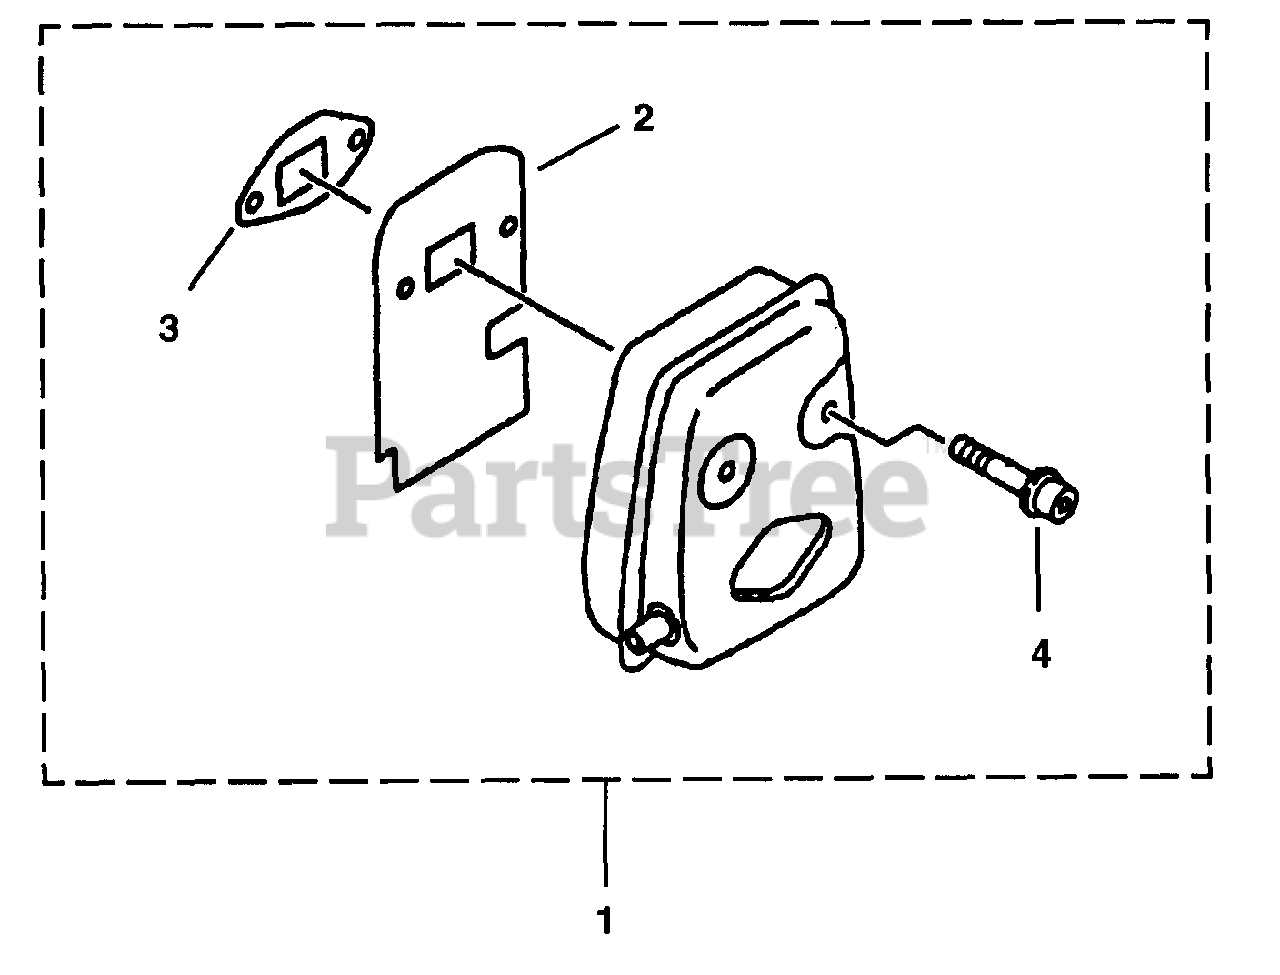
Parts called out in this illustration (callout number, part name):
1	MUFFLER ASSEMBLY
2	INSULATOR-Muffler
3	GASKET-Muffler
4	SCREW-Socket Hd. (M5 x 40 W)
